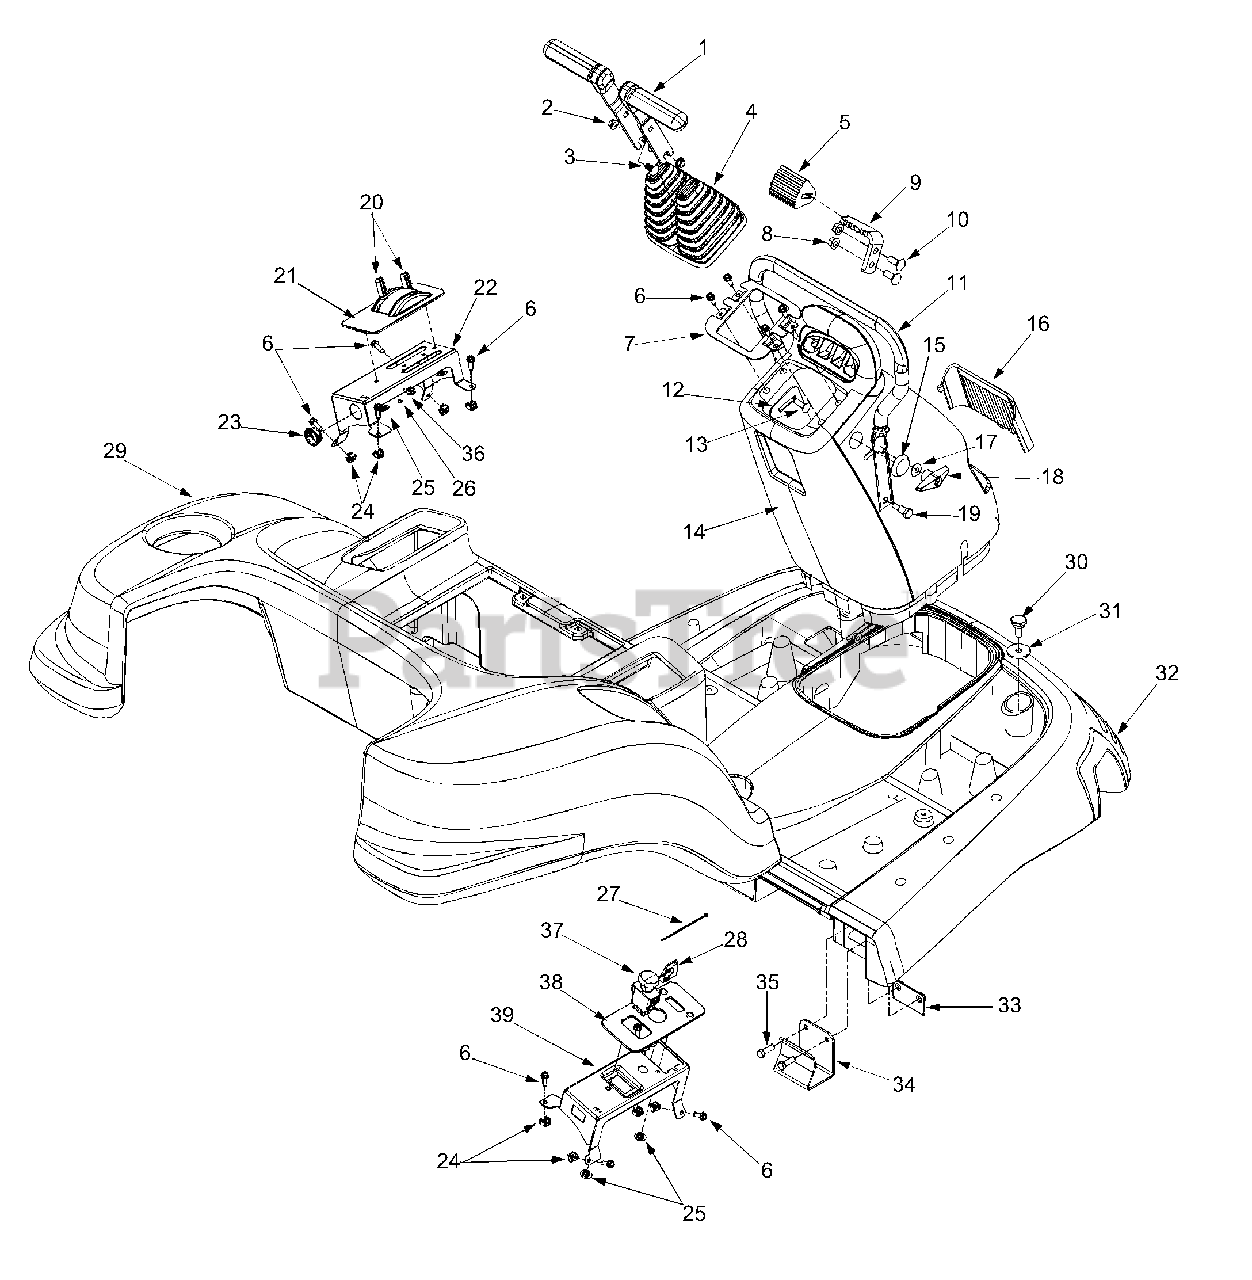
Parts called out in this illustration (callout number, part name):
1	Control Handle
2	Flange Lock Nut 5/16-18
3	Carriage Bolt 5/16-18
6	Hex Washer Screw 1/4-20 x .75
17	Bell Washer .340 ID x .872 OD
18	Wing Nut Knob
19	Shoulder Screw
21	LH Control Panel Cover
24	Retainer Nut 1/4-20
25	Push Nut
30	Shoulder Screw 3/8-16
31	Flat Washer .406 ID x 1.5 OD
33	Body Plate Assembly
36	Spring Clip
37	Electric PTO Switch
38	RH Control Panel Cover
